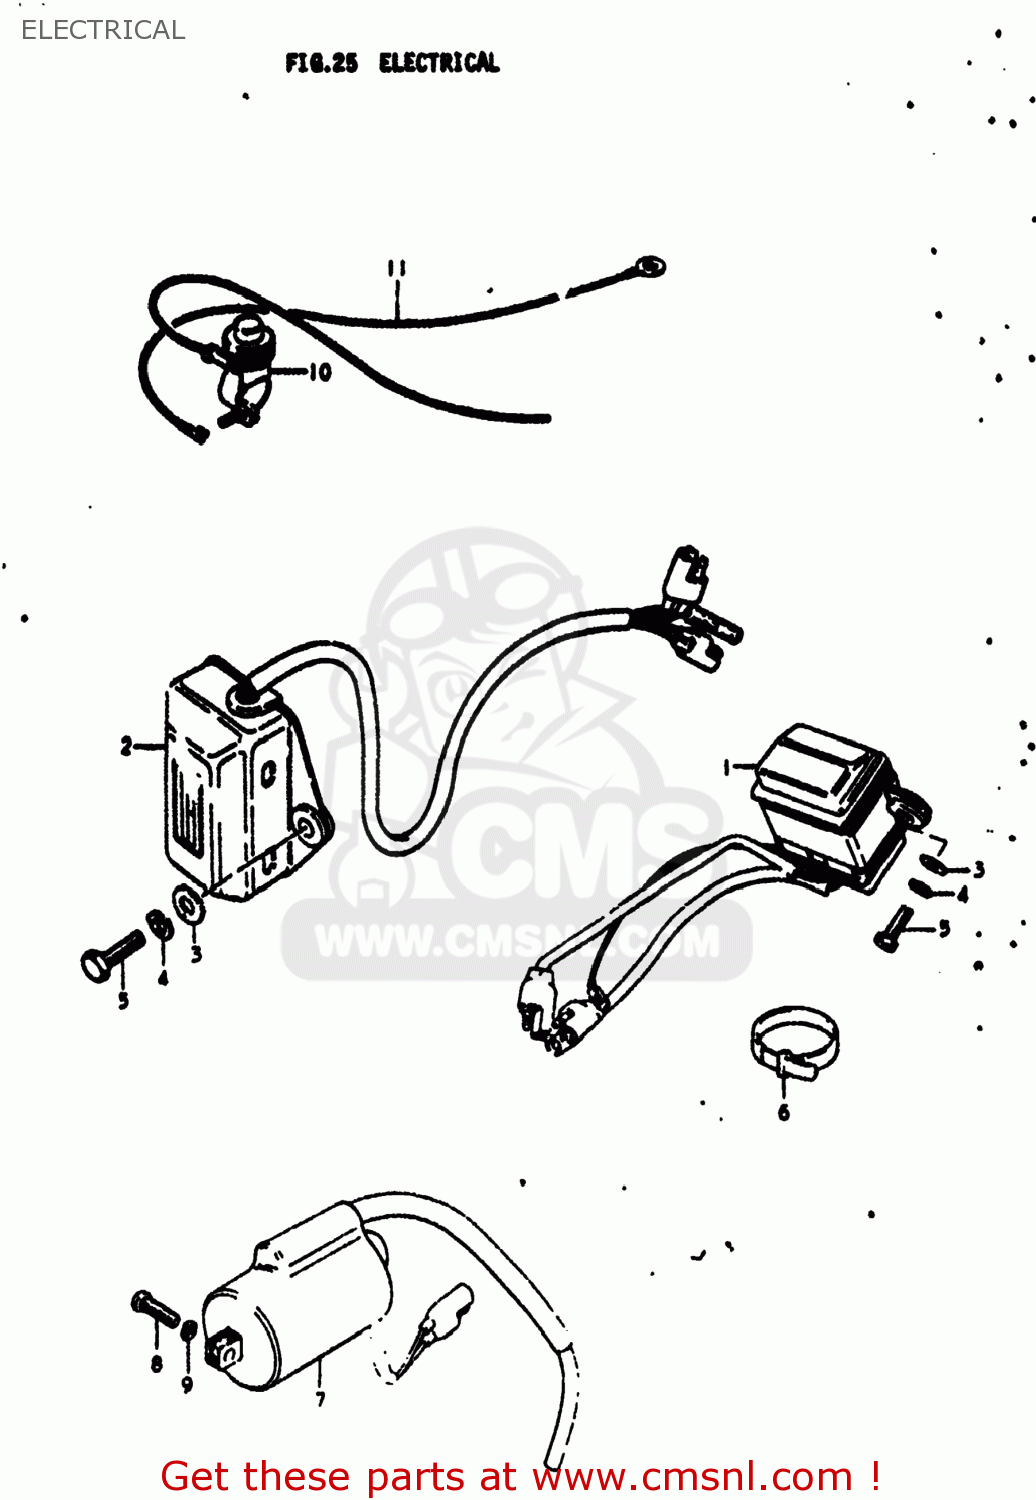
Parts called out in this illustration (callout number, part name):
2	CDI UNIT ASSEMBLY
3	WASHER 6MM
4	LOCK WASHER
5	BOLT
6	CLAMP
7	COIL ASSY,IGNITION
8	SCREW 5X20
9	LOCK WASHER
10	SWITCH ASSEMBLY
11	WIRE,ENGINE STOP EARTH
